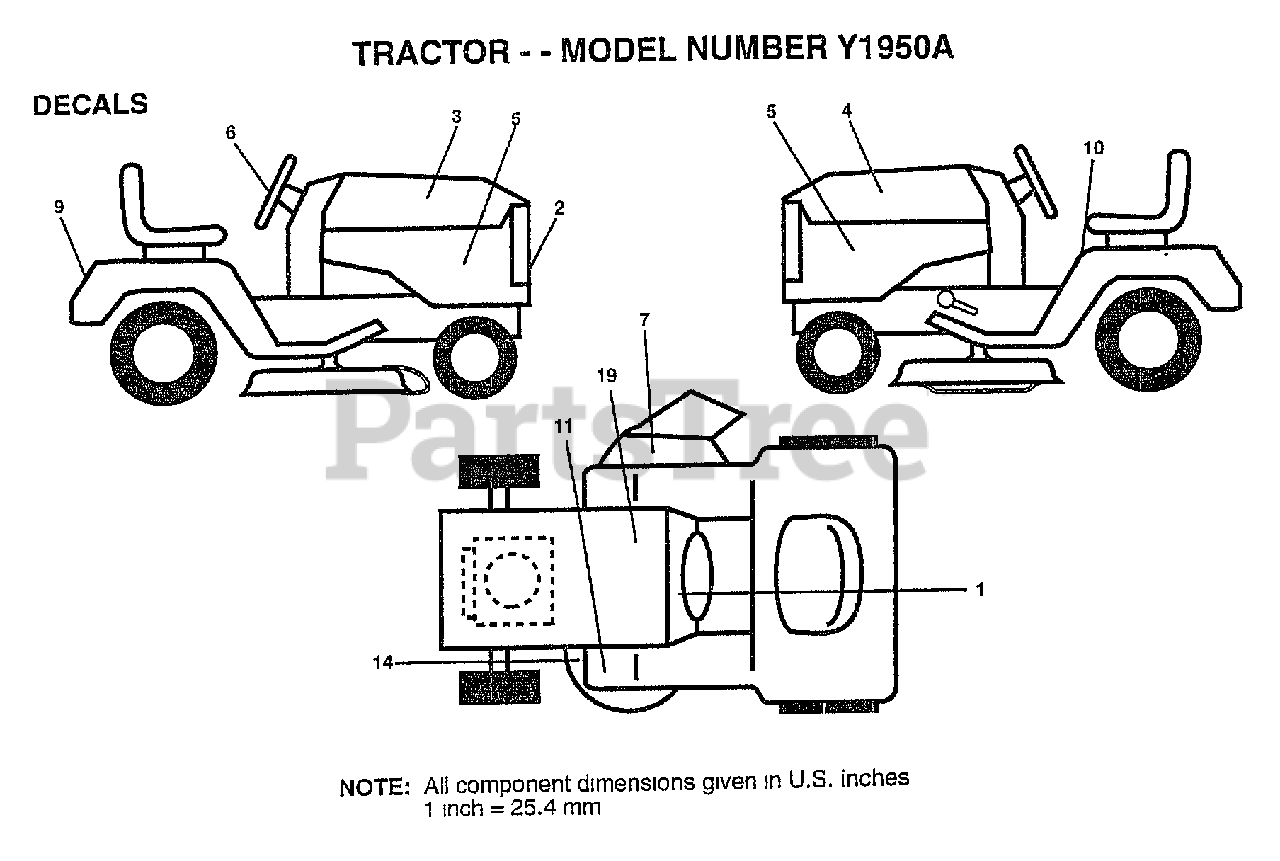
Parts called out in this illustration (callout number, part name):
1	DECAL.DASH.INSTR.
2	DECAL.GRILL.YARDP
4	DECAL HOOD LH
5	DECAL.PNL.SD.19HP
6	DECAL.INS.WHL.STG
7	"DECAL, WARNING"
10	DECAL CAUTION
11	DECAL T
14	"DECAL.V.BELT.44"""
19	DECAL
